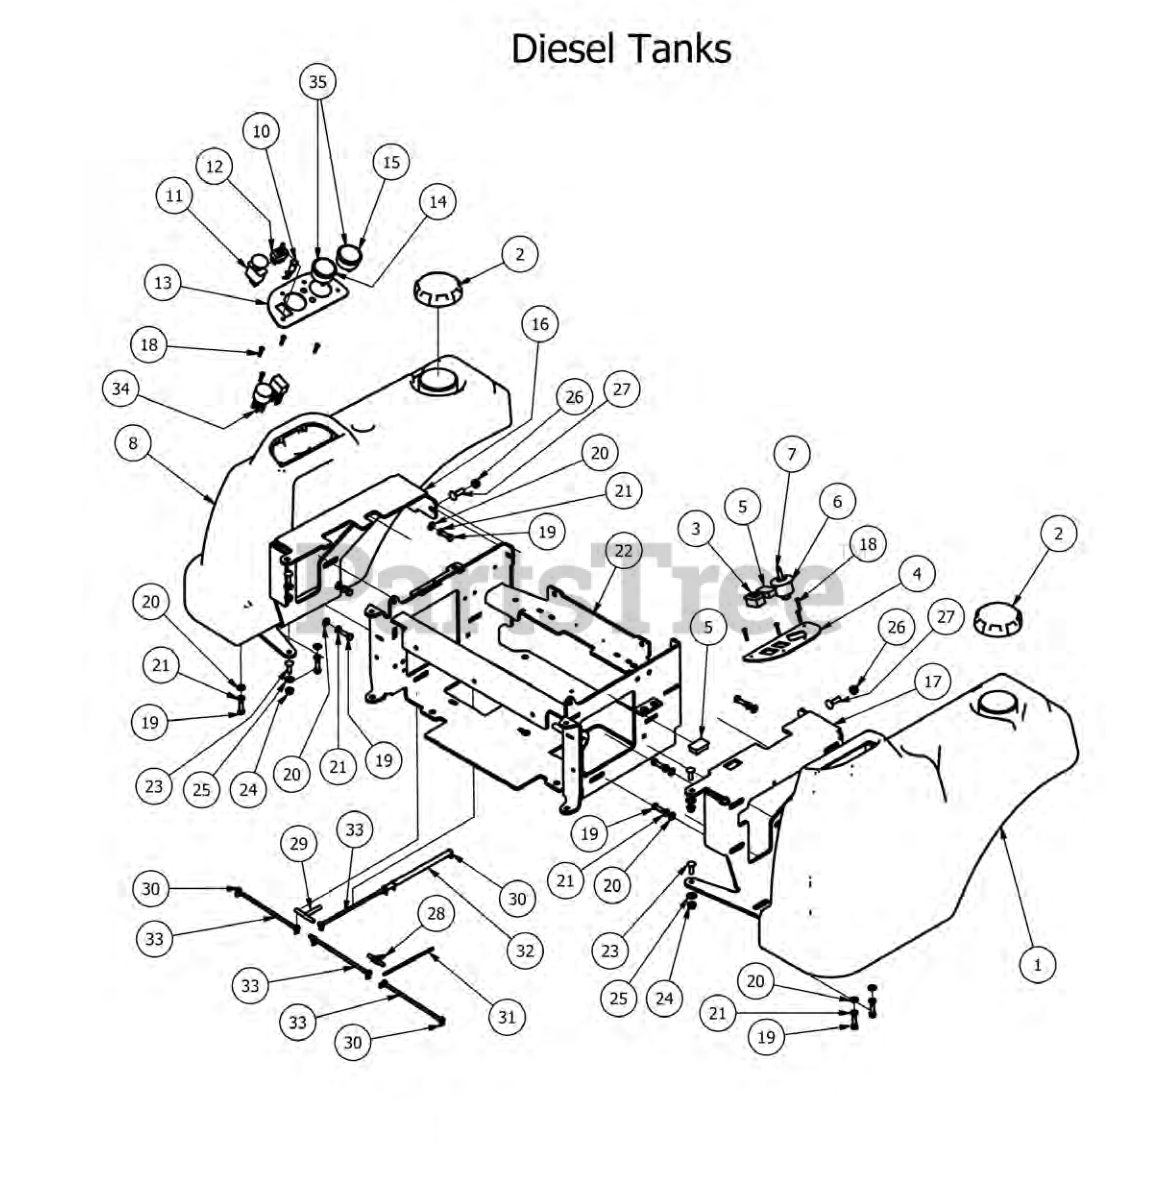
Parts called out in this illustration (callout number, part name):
1	Left Fuel Tank with Fender
2	Diesel Fuel Cap-3.5 inch Neck
3	Hour Meter
4	Control Panel (Left)
5	Light Plug
6	Ignition Switch
7	Ignition Key
8	Right Fuel Tank with Fender
9	Diesel Fuel Cap -3.5 inch Neck
11	PTO Engager
12	Deck Lift Joystick
13	Diesel Control Panel Right 2012
14	2" Water Temperature Gauge
15	2" Oil Pressure Gauge
16	Left Tank Support AOS
17	Right Tank Aupport AOS
18	10-32 x 1 Button Head Bolt
19	5/16" x 1" Bolt
20	5/16" Flat Washer
21	5/16" Lock Washer
22	Diesel Seat Frame
23	5/16" x 1" Carriage Bolt
24	5/16" Flange Nut
25	.360 ID Plastic Washer
26	3/8" Nylock Flange Nut
27	3/8" x 1 1/4" Carriage Bolt
28	Brass fuel line. T
29	fuel line T
30	1/4 fuel clamp
31	3/16 Fuel Line
32	5/16" fuel line hose
33	1/4" fuel line hose
34	Wiring Harness -35 & 28 Diesel
35	Pigtail-2" Faria Gauge -2012 (Used For the water and Oil Gauges)
